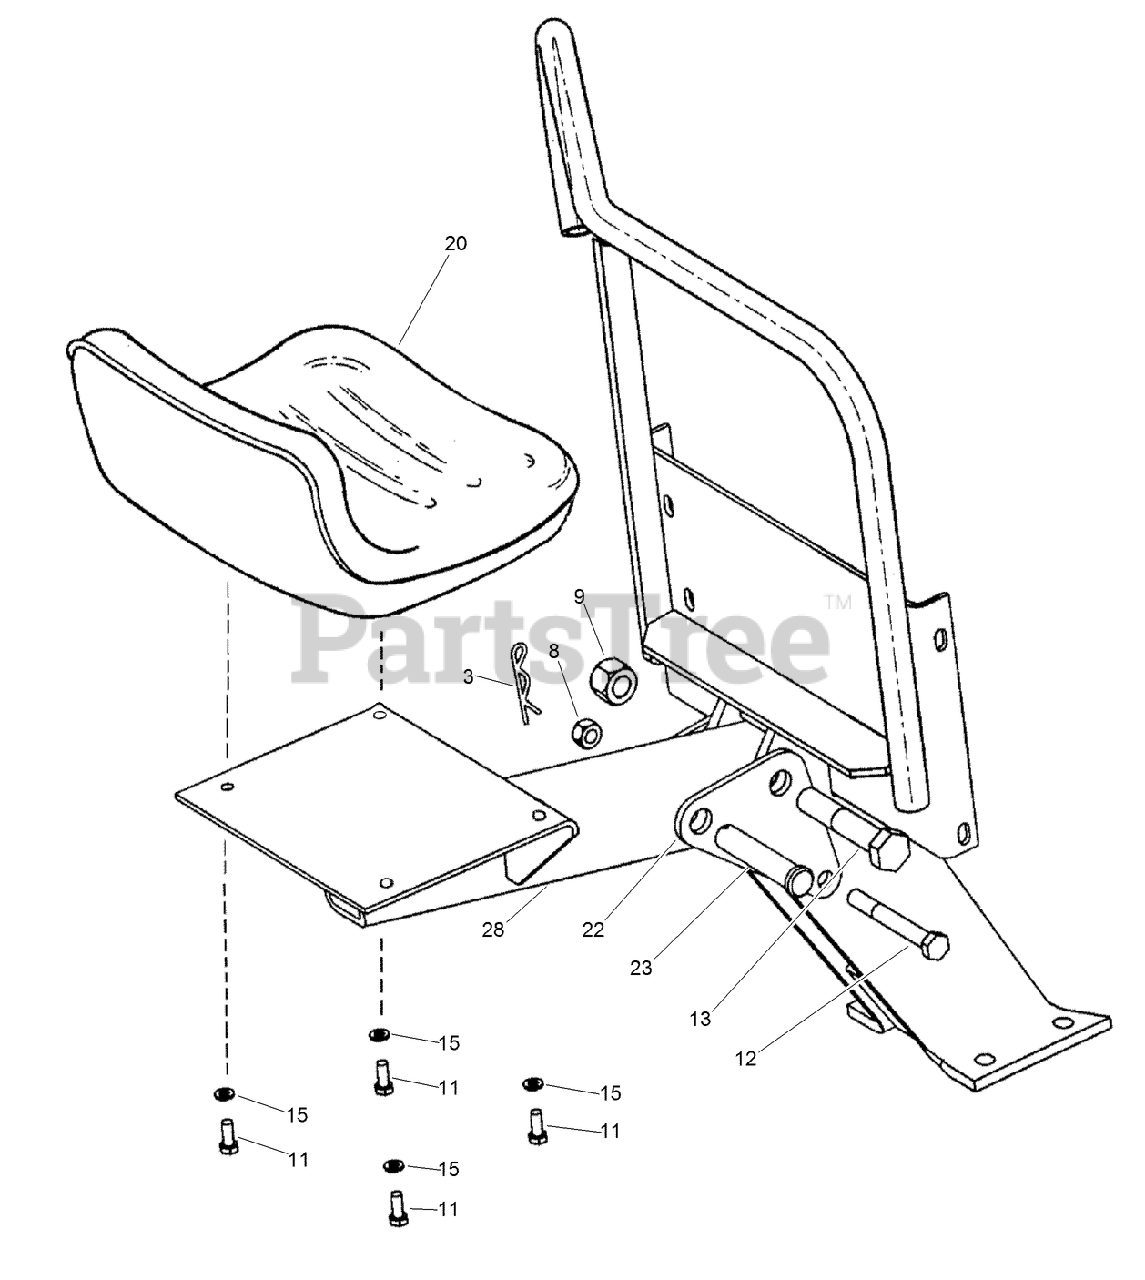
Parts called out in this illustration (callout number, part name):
3	PIN-HAIR COTTER, INT
8	NUT-LOCK, HEX
9	NUT-HEX LOCK
12	SCREW-HH
15	WASHER-Lock, 5/16 inch
20	SEAT-BLACK, LOW-BACK
22	PLATE-Seat Mounting
23	PIN-MOUNT, SEAT
28	POST-Seat, Backhoe
